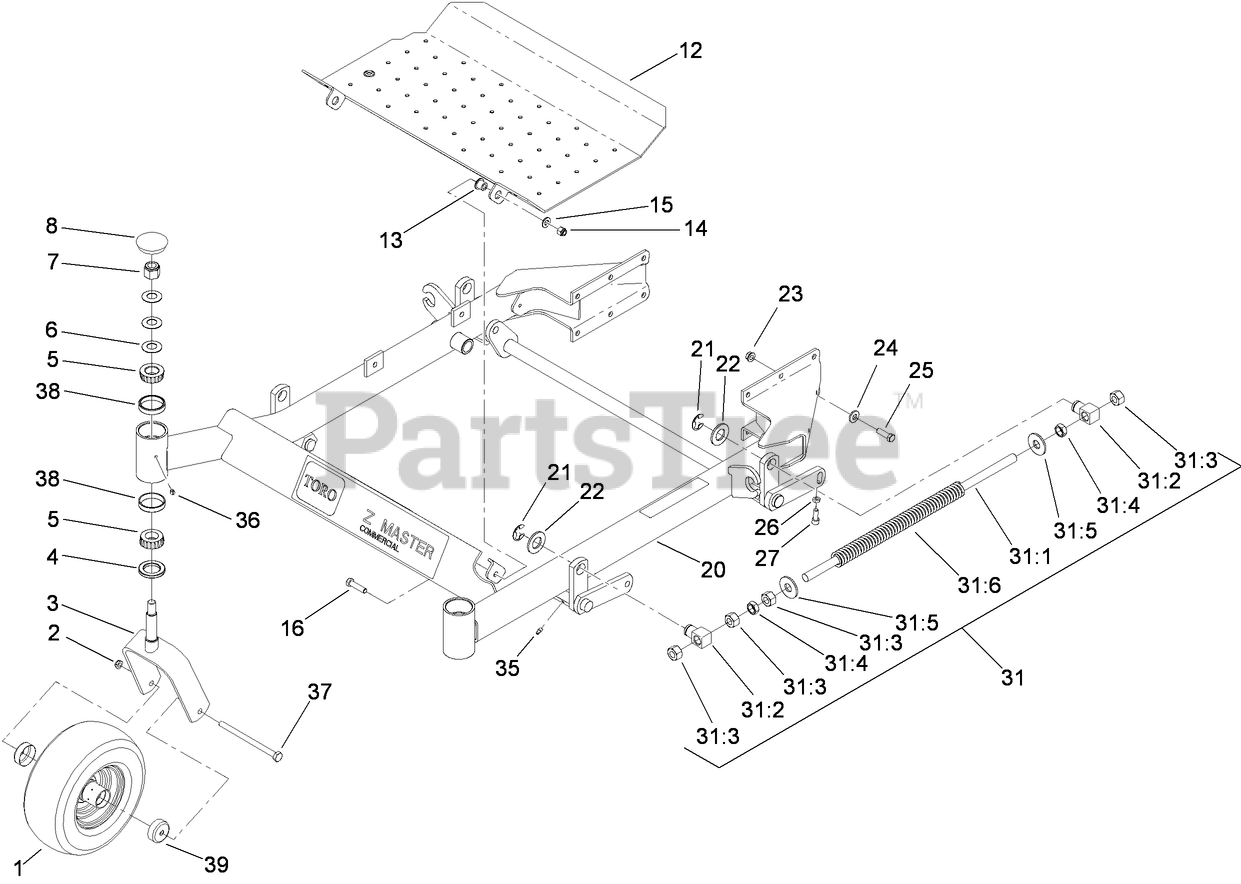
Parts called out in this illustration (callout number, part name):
1	WHEEL AND BEARING ASM
2	NUT-LOCK, NI
3	CASTER
4	SEAL-GREASE
5	BEARING-CONE, TAPERED
6	WASHER-BELLVILLE
7	NUT-LOCK, NI
8	CAP-GREASE
12	FLOOR PAN
13	BUSHING-FLANGE
14	NUT-LOCK, NI
15	WASHER-FLAT
16	SCREW-HH
20	FRONT FRAME ASM
21	RING-RETAINING, EXT
22	WASHER-FLAT
23	NUT-HHF, WHIZ
24	WASHER-BELLEVILLE
25	SCREW-HH
26	NUT-JAM
27	SCREW-HSH
31	FRONT FRAME SPRING ASM
31:1	ROD-LIFT, DECK
31:2	SWIVEL-DECK MOUNT, REAR
31:3	NUT-HEX
31:4	NUT-JAM
31:5	WASHER-FLAT
31:6	SPRING-SUPPORT, DECK
35	FITTING-GREASE
37	SCREW-HH
38	BEARING-CUP, TAPERED
39	GUARD-SEAL
